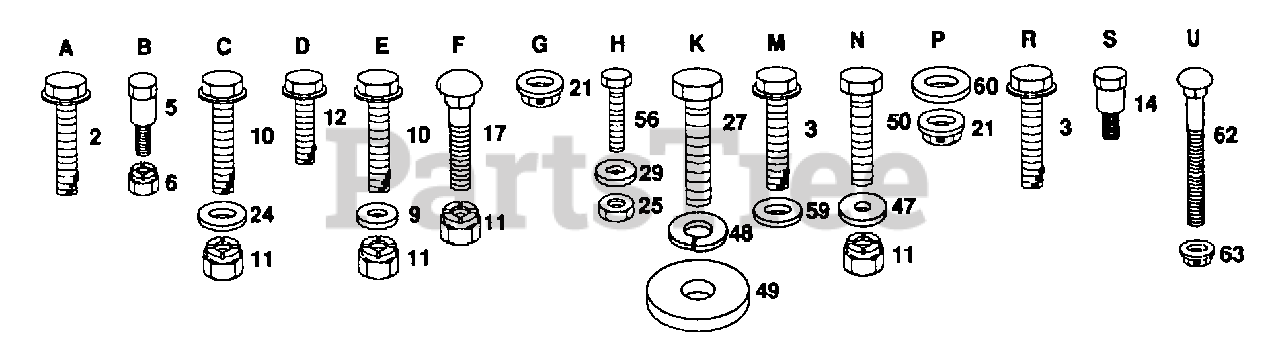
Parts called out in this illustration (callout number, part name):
2	SCREW
3	SCREW GTV
9	WASHER
12	SCREW LT
17	BOLT
21	PAL NUT LT
24	WASHER
25	NUT
27	BOLT
47	WASHER
48	LOCKWASHER
49	WASHER
50	BOLT
56	SCREW SPECIAL
59	WASHER
60	WASHER PM
62	BOLT
